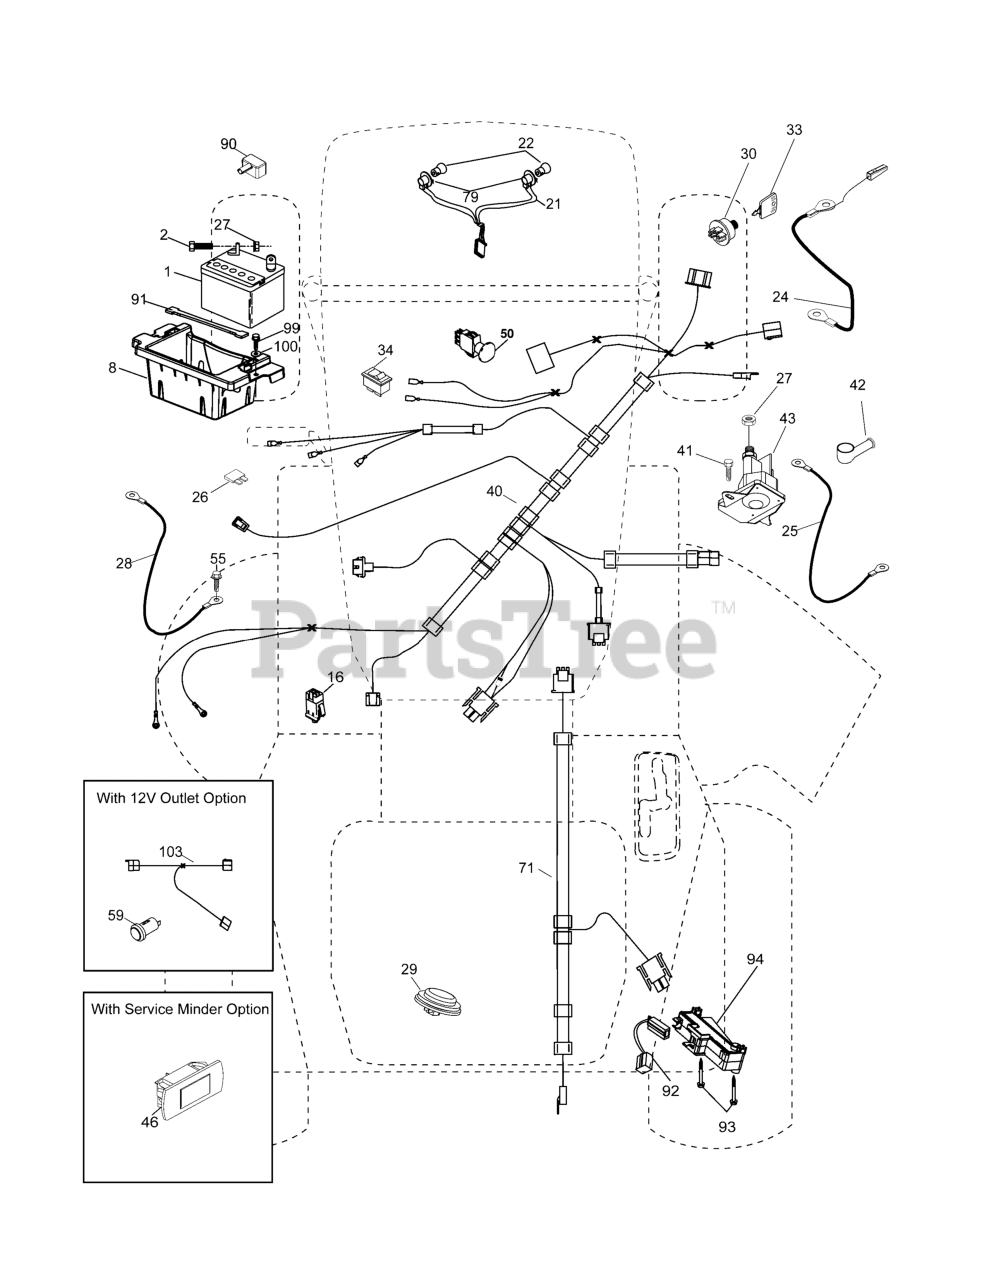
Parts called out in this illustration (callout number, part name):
1	BATTERY
2	BOLT, Hex Head ,1/4-20 unc x 3/4
8	BOX, Battery
16	SWITCH, Interlock
21	HARNESS ASSEMBLY, Light (w/4152j
22	BULB, Light #1156
24	CABLE, Battery 6 Ga. 11" Red
25	CABLE, Starter
26	FUSE, 20 Amp
27	NUT, Hex Keps, 1/4-20 unc
28	CABLE, Ground
29	SWITCH, Seat
30	SWITCH, Ignition
33	KEY/ CHAIN
34	SWITCH, Light/Reset
40	HARNESS, Ignition
41	BOLT, Hex, 1/4-20 (Black Finish)
42	COVER, Terminal, Red
43	SOLENOID
79	SOCKET ASSEMBLY, Bulb Twistlock
90	COVER, Terminal Battery
92	HARNESS, Pigtail
93	SCREW, Plastite, 10-14 x 2.0
94	MODULE, Reverse
99	Screw Hexwsh Thdrol 1/4-20 x 3/4
100	Washer 9/32 x 7/8 x 16 Ga.
103	Harness Pigtail 12V Outlet
